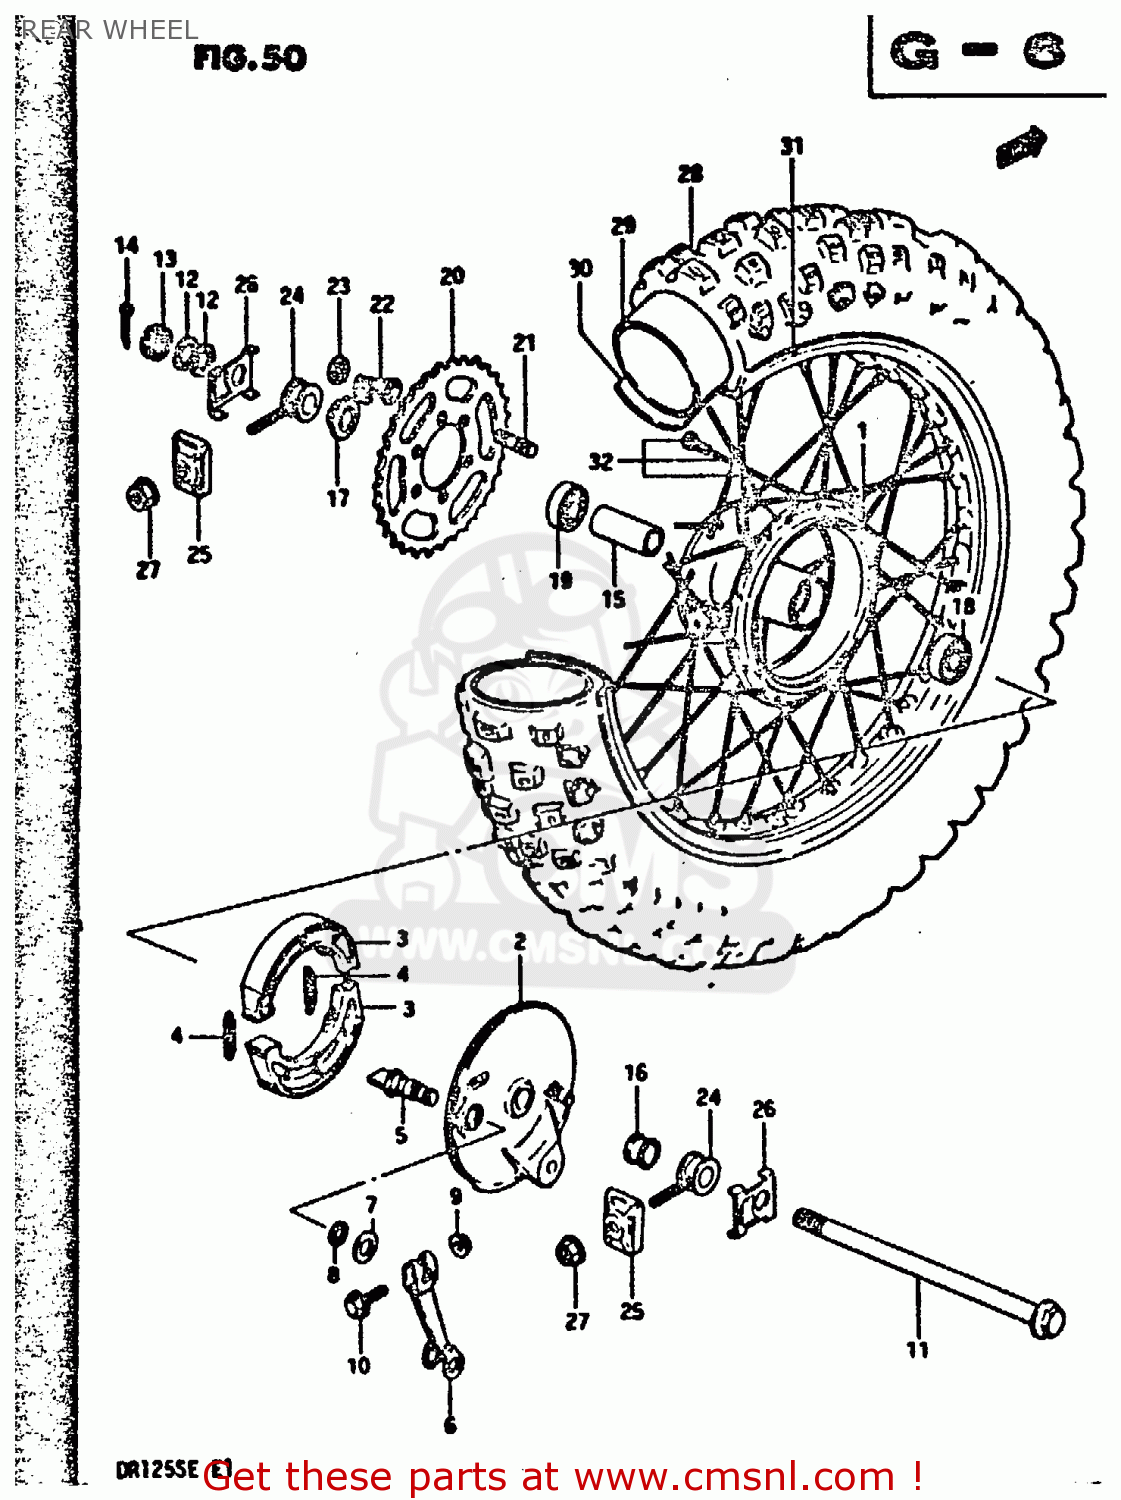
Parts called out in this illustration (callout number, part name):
1	HUB,REAR WHEEL
2	PANEL,RR BRAKE ANCHOR
3	SHOE,BRAKE
4	SPRING(L:34)
5	CAM,FRONT BRAKE
6	LEVER,RR BRAKE CAM
7	WASHER (14.5X22X1.6)
8	O-RING (D:2.4 ID:13.8)
9	NUT
10	BOLT
11	AXLE,REAR
12	WASHER
13	NUT
14	COTTER PIN
15	SPACER(15.3X21.7X107.5)
16	SPACER,RR AXLE,R
17	SPACER,REAR AXLE,LEFT
18	BEARING
19	BEARING
20	SPROCKET,RR(NT:47)
21	BOLT
22	WASHER
23	NUT
24	ADJUSTER,CHAIN
25	PLATE,CHAIN ADJUSTER
26	WASHER,CHAIN ADJUSTER GUIDE
27	NUT
28	TIRE
29	TUBE ASSEMBLY,WHEEL,INNER
30	PROTECTOR,INNER TUBE
31	RIM,REAR WHEEL
32	SPOKE SET
